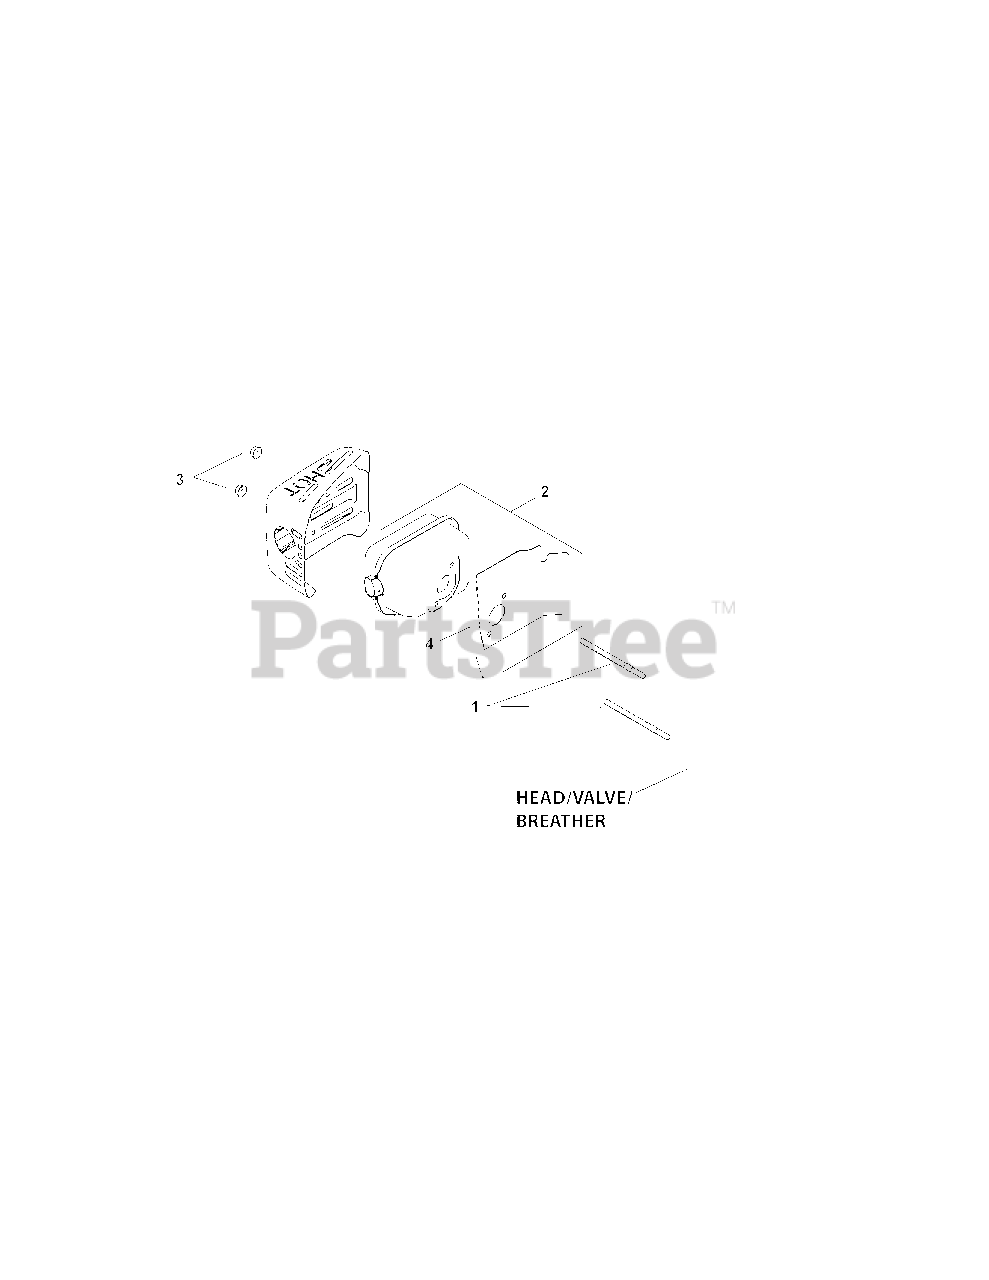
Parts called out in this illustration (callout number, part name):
1	Stud Kit (M6)
3	Nut, Hex Flange Lock, M6
4	Muffler Gasket
